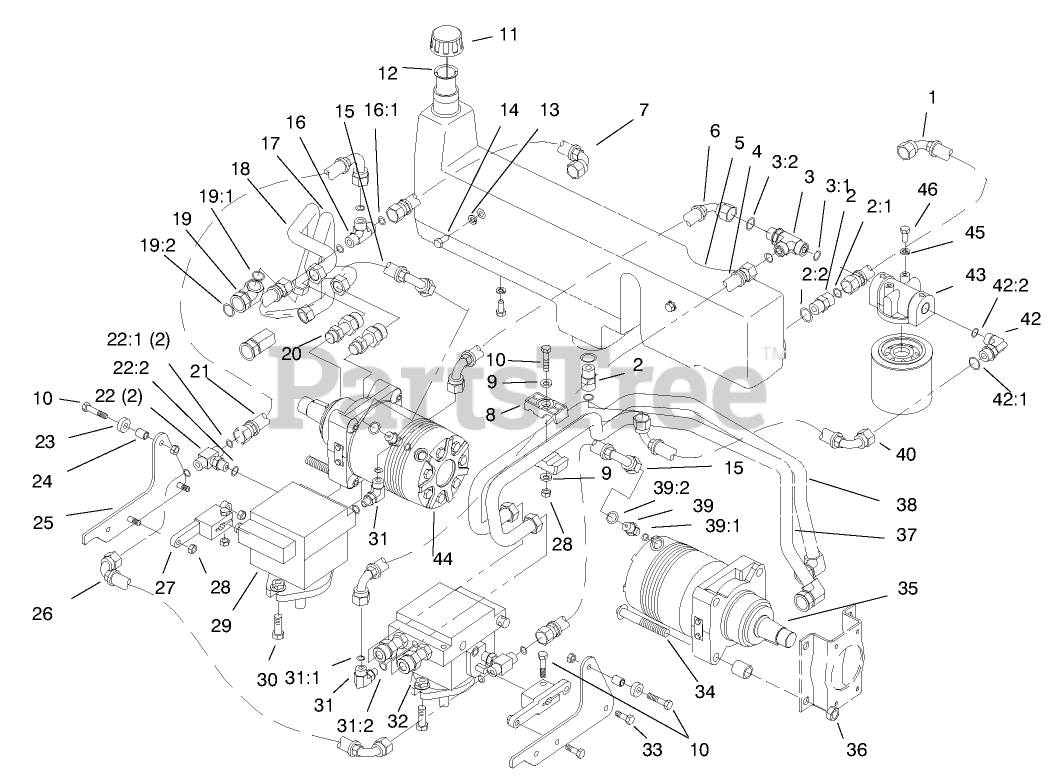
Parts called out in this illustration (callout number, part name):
1	ASSEMBLY - HYDRAULIC HOSE
2	FITTING-STRAIGHT
2:1	O-RING
2:2	O-RING
3	FITTING-TEE
3:1	O-RING
3:2	O-RING
4	ASSEMBLY - HYDRAULIC HOSE
5	RESERVOIR - OIL
6	ASSEMBLY - HYDRAULIC HOSE
7	ASSEMBLY - HYDRAULIC HOSE
8	CLAMP-TUBE
9	WASHER-PLAIN
10	SCREW-HH
11	ASM - OIL CAP
12	SCREEN - FILLER
13	WASHER-LOCK
14	SCREW-HH
15	ASSEMBLY - HYDRAULIC HOSE
16	TEE - 11/16 ORS
16:1	O-RING
17	Tube ASM-Right
18	Tube ASM-Right
19	FITTING-ELBOW-90
19:1	O-RING
19:2	O-RING
20	Fitting-Hydraulic
21	ASSEMBLY - HYDRAULIC HOSE
22	ADAPTER
22:1	O-RING
22:2	O-RING
23	BEARING-BALL
24	SPACER-LEVER, CONTROL
25	Arm-Follower
26	ASSEMBLY - HYDRAULIC HOSE
27	ARM-PUMP
28	NUT-LOCK, NI
29	HYDRAULIC PUMP
30	SCREW-HH
31	FITTING-ELBOW 90
31:1	O-RING
31:2	O-RING
32	NUT-HF
33	SCREW-HH
34	SCREW-HSH
35	MOTOR - WHEEL LH
36	NUT-LOCK, NI
37	Tube ASM-Left
38	Tube ASM-Left
39	FITTING-STRAIGHT
39:1	O-RING
39:2	O-RING
40	ASSEMBLY - HYDRAULIC HOSE
41	CARTRIDGE-FILTER, OIL
42	FITTING-ELBOW-90 DEG
42:1	O-RING
42:2	O-RING
43	HEAD-FILTER
44	MOTOR - WHEEL RH
45	WASHER-LOCK
46	SCREW-HH
